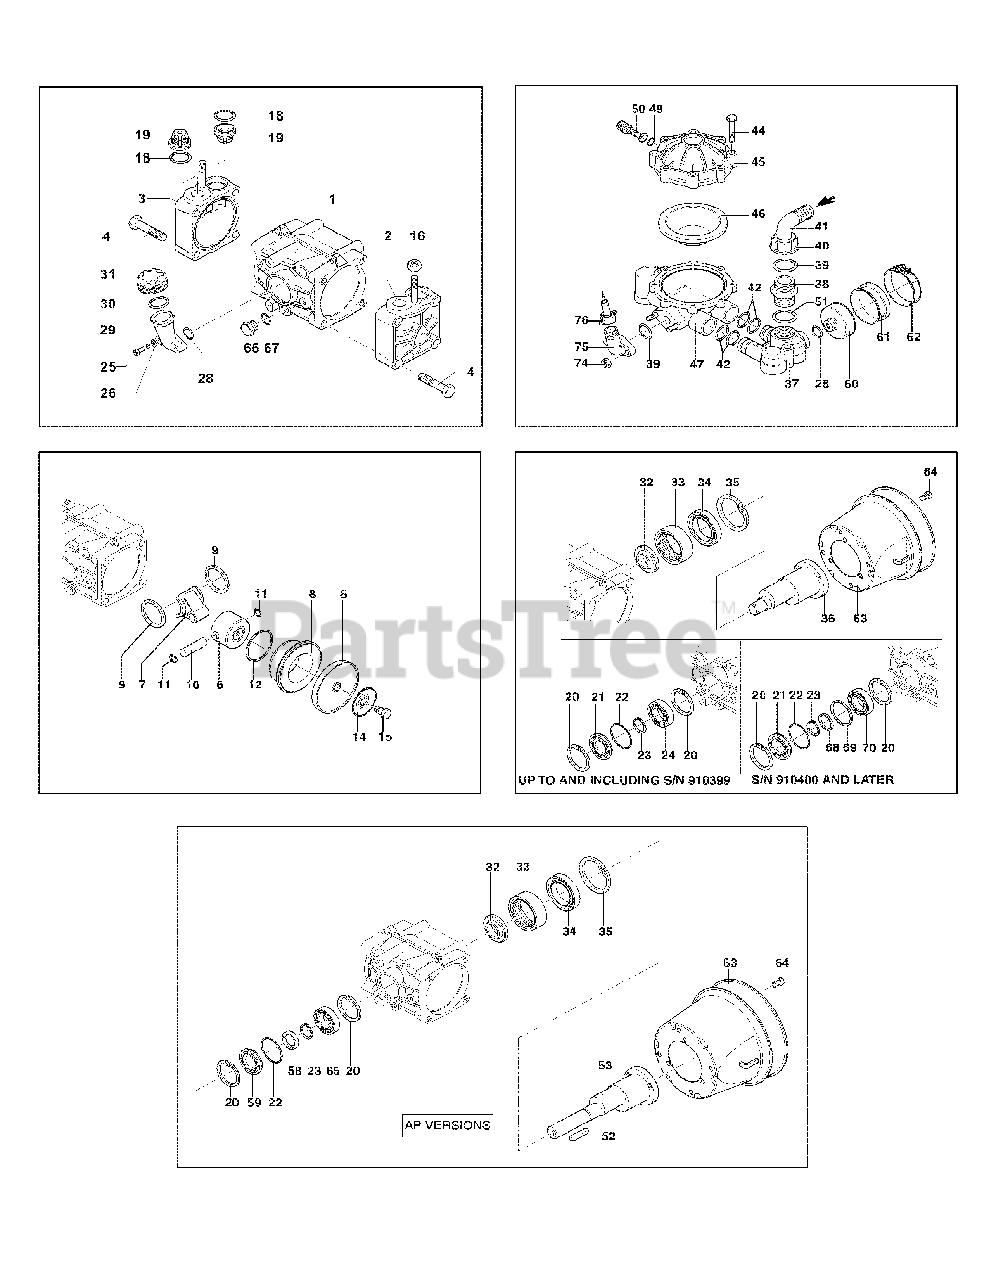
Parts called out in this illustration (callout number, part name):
1	Pump Body w/bolts
2	Right Head Assembly (DX)
3	Left Head Assembly (SX)
5	Diaphragm, Desmopan (Std.)
5	Diaphragm, Buna-N (Opt.)
7	Connecting Rod
9	Retainer Ring
10	Connecting Rod Pin
14	Retaining Washer
15	Diaphragm Bolt
19	Complete Valve Assembly
20	Retaining Ring
23	Retaining Ring
29	Oil Sight Glass
31	Oil Sight Glass Cap
33	Roller Bearing
35	Retaining Ring
37	Suction Manifold
38	Threaded Adapter
45	Upper Air Chamber
46	Accumulator Diaphragm, Buna-N
47	Lower Air Chamber Body
60	Diaphragm Holder
61	Suction Diaphragm
64	M10 X 16 Bolt
66	Drain Plug, oil
76	1/2" Fitting plus Hose Barb
